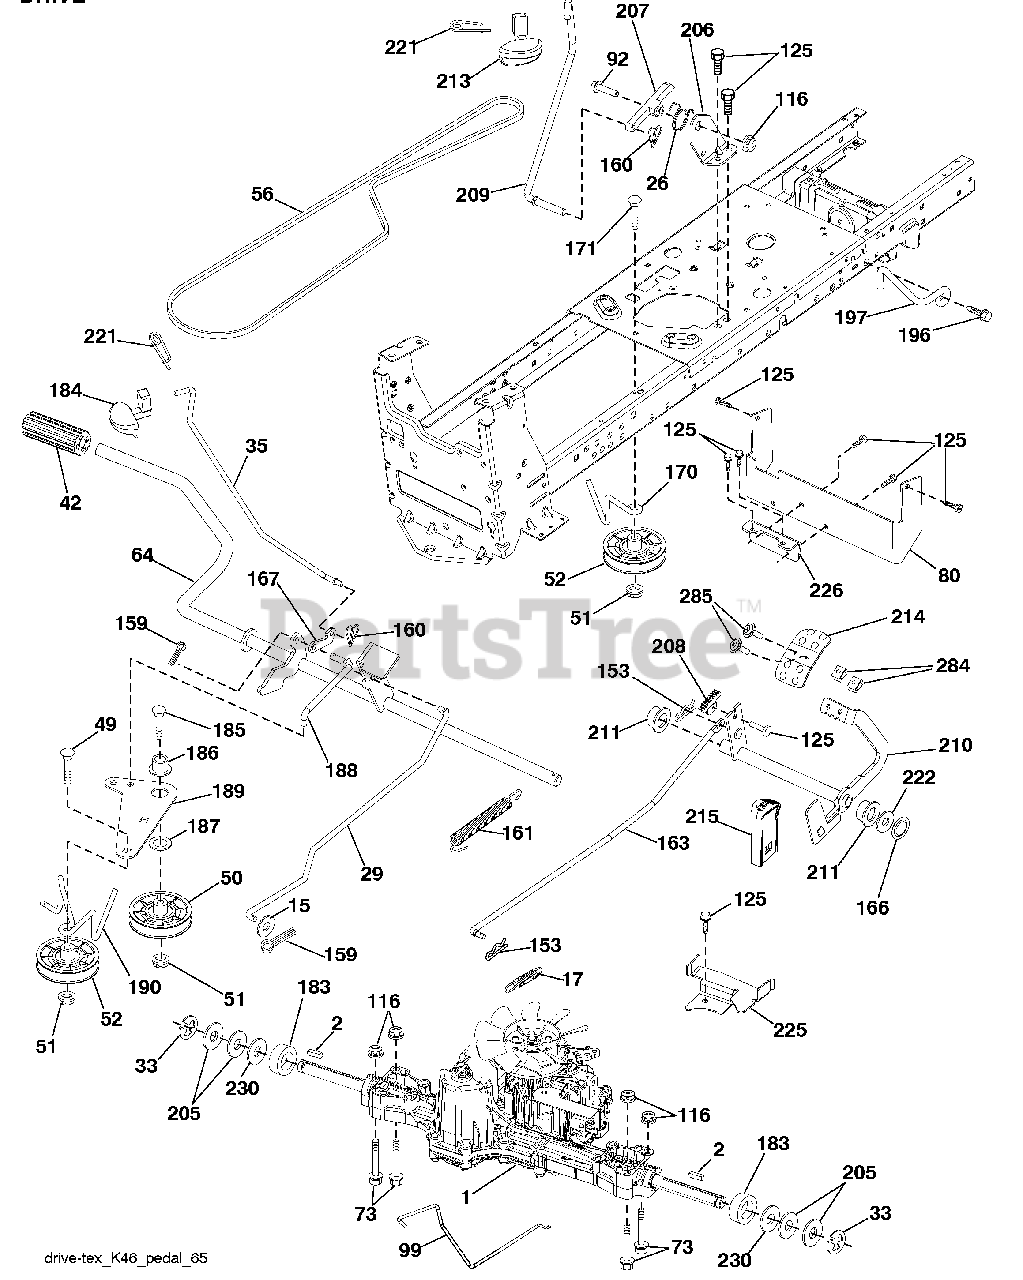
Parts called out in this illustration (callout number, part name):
1	Transaxle, TUFFTORQ K46BT
15	Washer 13/32 x 13/16 x 16 Ga.
17	Spring, Brake
26	Spring Return Cruise
29	Rod, Brake
35	Rod, Brake, Park
42	Cover, Foot Pedal
50	Pulley Idler Flat
51	Lock Nut 3/8-16
52	Idler V-Groove 910" Offset
56	V-Belt, Drive
64	Shaft Asm. Pedal Brake Control
73	Bolt Hex Flghd 5/16-18 Gr. 5
80	Bracket Strap Torque
92	Bolt Fin Hex 5/16-18 unc x 1.25
99	Rod Spring Bypass
116	Nut Lock Hex Flange 5/16-18
125	Screw 5/16-18 x 3/4
153	Retainer Spring
159	Pin Cotter 1/8 x 3/4
160	Retainer Clip
161	Spring, Return, Clutch
163	Rod Pedal Control
166	Nut Push
167	Latch Brake Parking
170	Keeper Belt Centerspan
171	Bolt RDHD SQNK 3/8-16 unc x 2
183	Spacer Split
184	Handle Parking Brake
185	Bolt Rdhd Sqnk 3/8-16 x 2-1/2
186	Spacer Retainer
187	Washer
188	Link Clutch Ground Drive
189	Bellcrank Ground Drive
190	Keeper Bellcrank Ground Drive
196	Screw 3/8-16 x 1
197	Bracket Clutch Anti-Rotation
206	Bracket Mount Latch Cruise
207	Latch Control Cruise
208	Gear Sector Control Cruise
209	Rod Control Cruise
210	Rocker Asm. Pedal Control
211	Bearing Nylon
213	Knob Control Cruise
214	Pedal Forward
215	Pedal Reverse
221	Retainer Spring Clip Handle
222	Washer 21/32 x 1-1/4 x 10 Ga.
225	Keeper Belt Trans.
226	Bracket Mount Torque
230	Washer Hardened
284	Nut U-CHNL 1/4-20 550DP .350 PNL
285	Screw PHD 1/4-20 Box Drive
